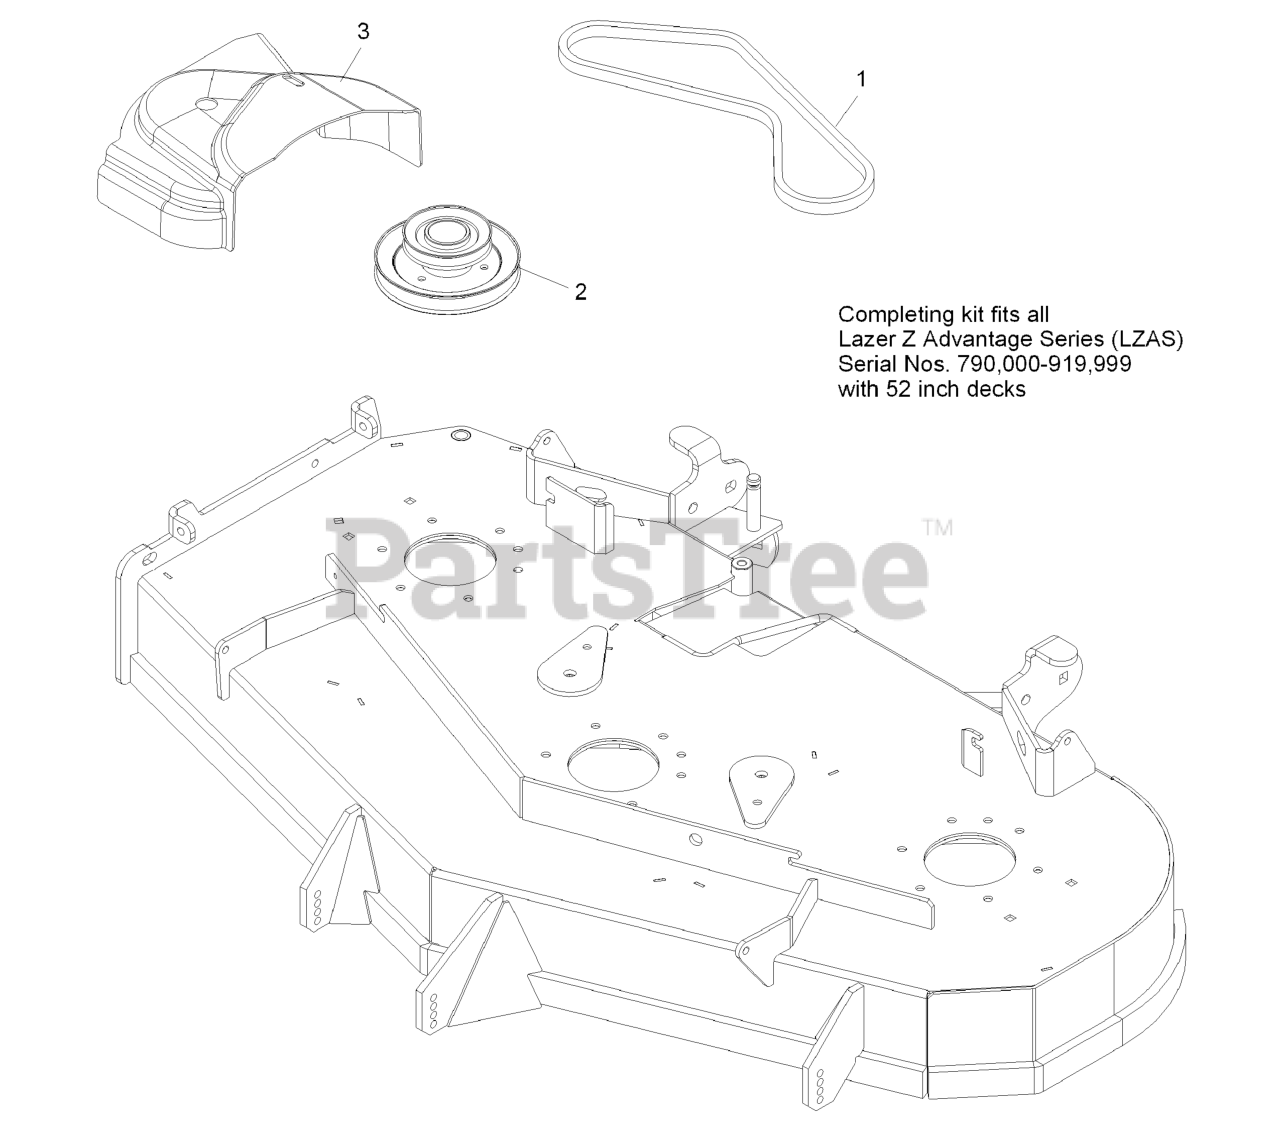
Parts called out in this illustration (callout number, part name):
1	BELT, BLOWER 52"DECK
2	JACKSHAFT,UV DRIVE 524
3	COVER,BELT UV 52
